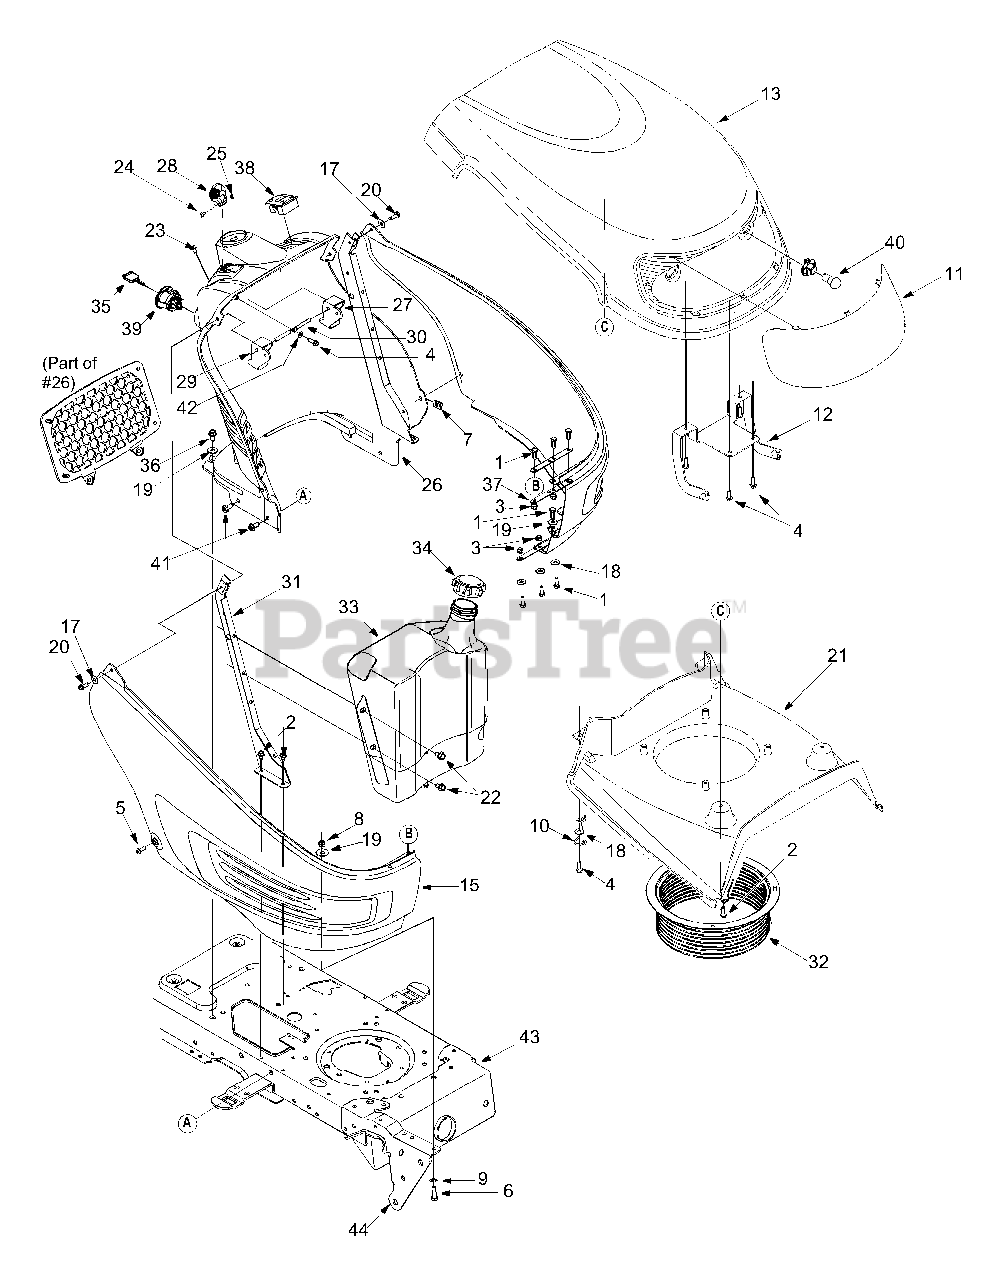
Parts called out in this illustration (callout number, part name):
1	Hex Cap Screw, 1/4-20 x .75
2	Self-tapping Screw, 1/4-20 x .5
3	Lock Nut, 1/4-20
4	Self-tapping Screw, 1/4-15 x .75
5	Pan Phillips Screw, 1/4-20 x .75
6	Hex Cap Screw, 5/16-18 x 1.0
7	U-type Speed Nut, 1/4-20
8	Lock Nut, 5/16-18
10	Hood Latch Rod
11	Head Light Lens
14	LH Side Panel
15	RH Side Panel
16	Lock Washer, 1/4
17	Flat Washer, .283 x .75 x .030
18	Flat Washer, .28 x .74 x .063
19	Flat Washer, .349 x 1.0 x .063
20	Self-Tapping Screw, 1/4-20 x 1.25
21	Hood Plenum w/o Intake Bellow
22	Self-Tapping Screw, 5/16-18 x .625
23	Torx Self-Tapping Screw, 1/4-14 x .625
24	Torx Screw, #8-32 x .375
25	Hex Nut, 8-32
26	Dash Panel, 4-style
27	Parking Brake Button
28	Throttle Control Lever
29	Cruise Control Button
30	Brake/Cruise Pivot Rod
32	Intake Bellow
33	Fuel Tank, 2-gallon
34	Fuel Cap
35	Ignition Key w/ plastic cover
35	Ignition Key w/o plastic cover
36	Self-tapping Screw, 5/16-18 x .75
39	Ignition Switch
40	Headlight Assembly
41	Self-tapping Screw, 5/16-18 x .75
